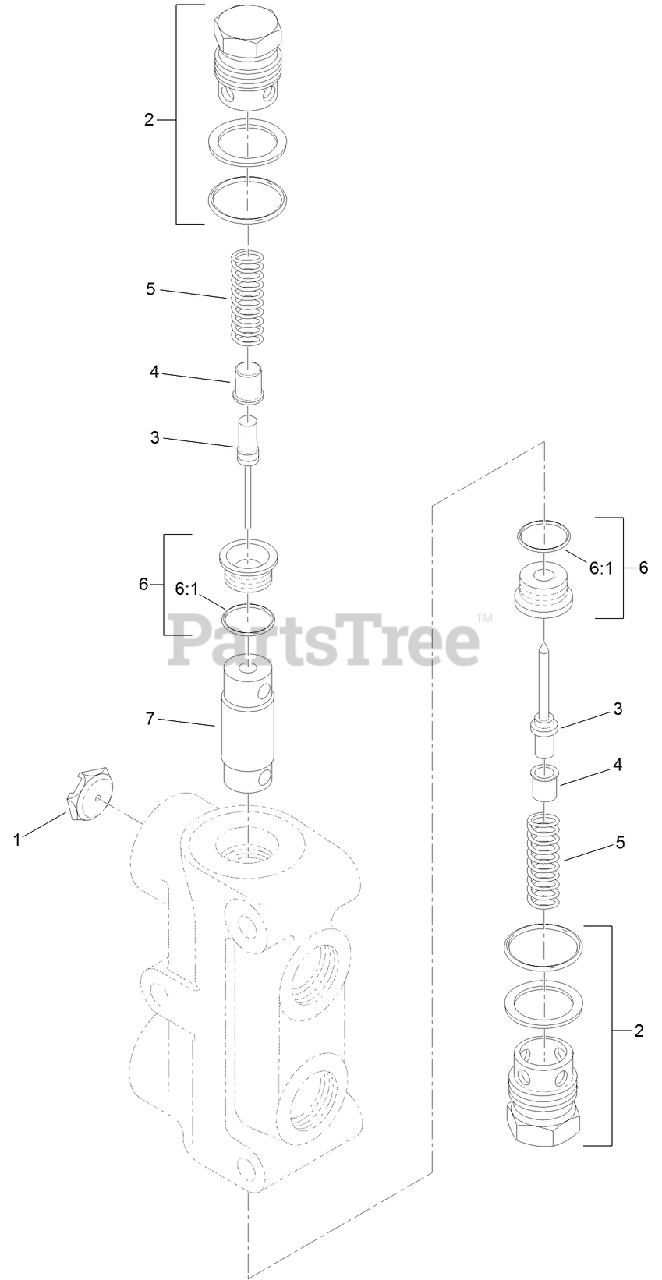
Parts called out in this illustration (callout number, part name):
1	PLATE-ORIFICE
2	PLUG ASM
3	POPPET
4	EYELET-POPPET
6	SEAT ASM
6:1	O-RING
7	PLUNGER
